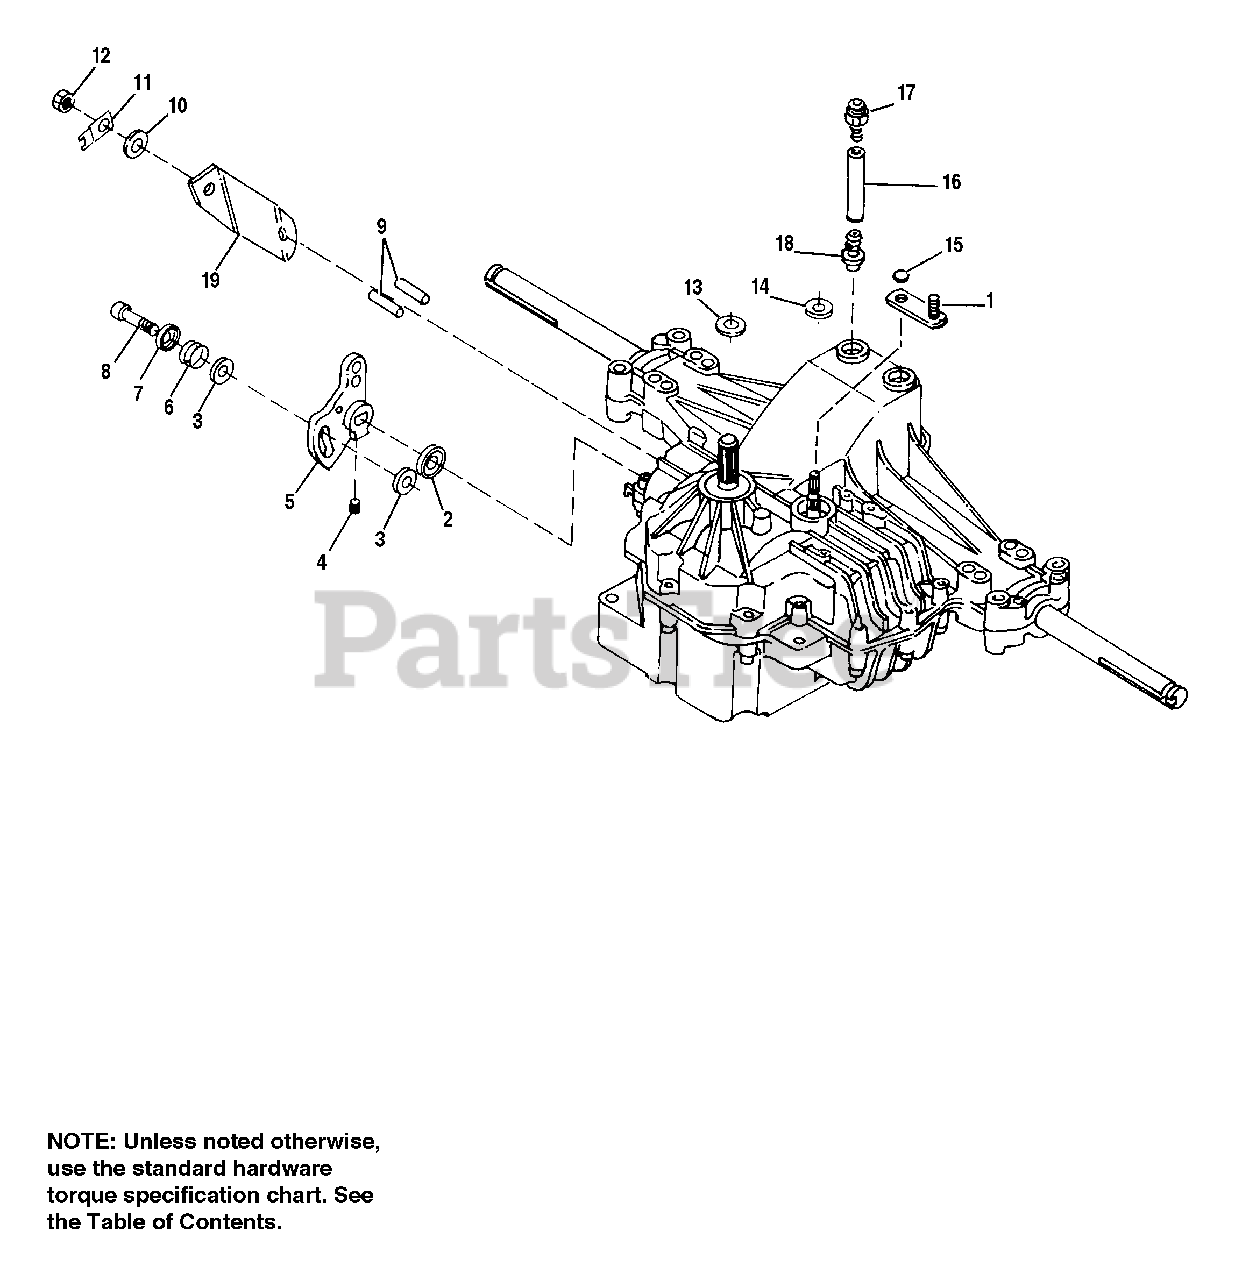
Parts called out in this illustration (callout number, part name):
1	ARM, Bypass
3	PUCK, Dampener
5	ARM, Control
8	SCREW, Socket Hd.
9	ACTUATOR PIN
10	WASHER, 7/16 x 7/8 x 1/16
11	LOCKING STRAP
12	NUT, Hex, Lock, 5/16 x 24
15	RING, Retaining
17	FITTING, Vent Plug
